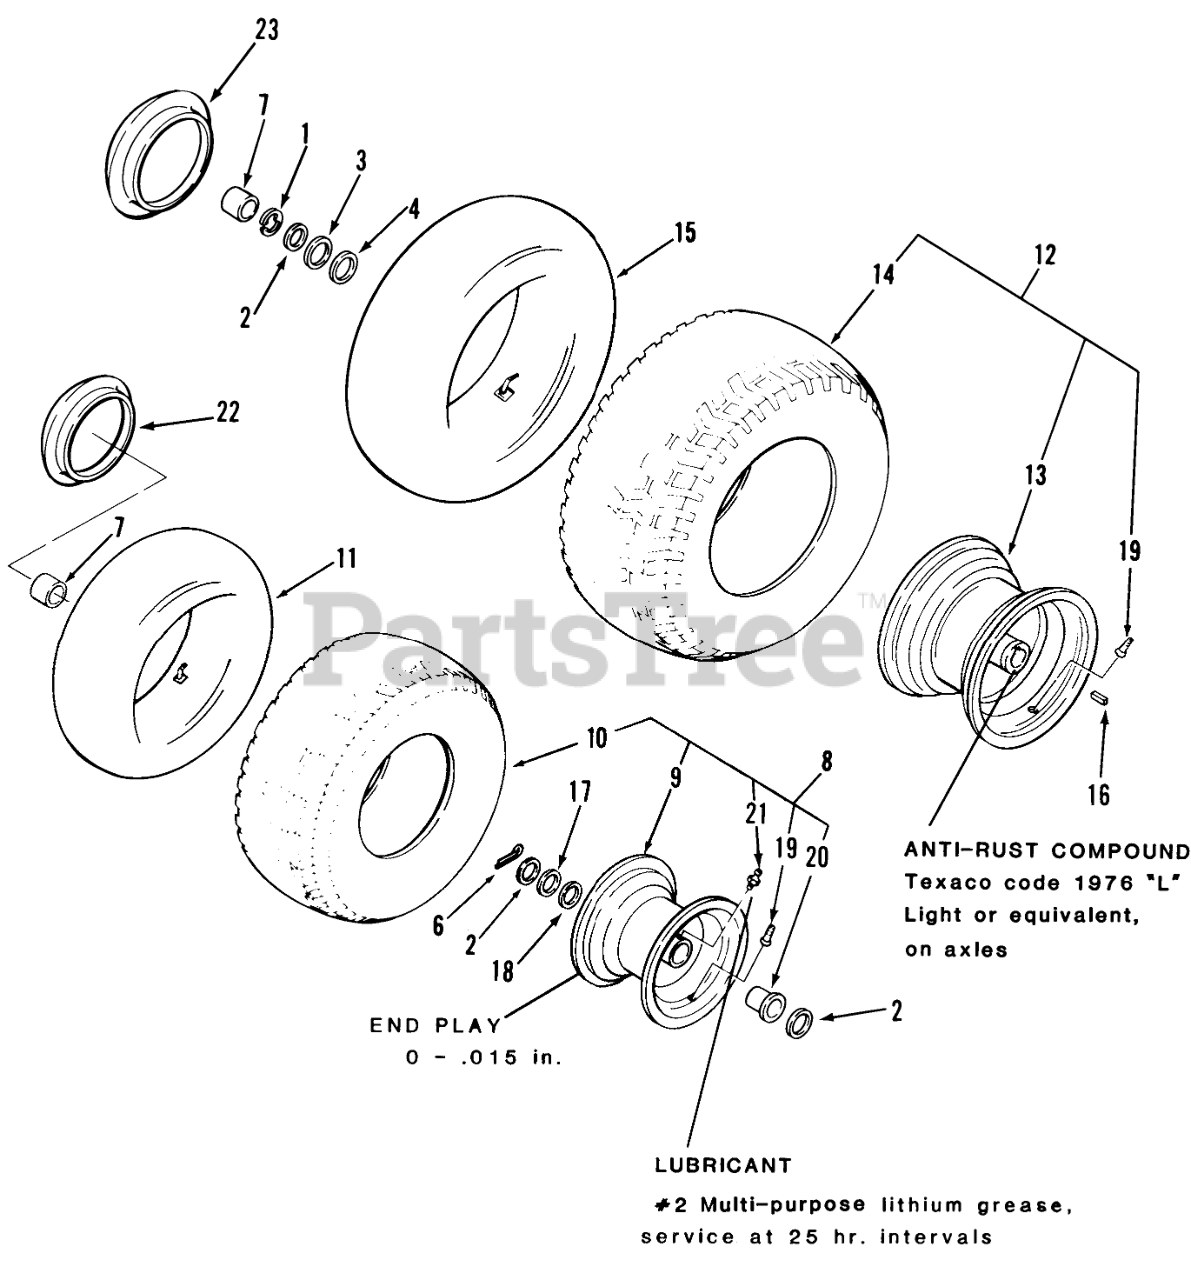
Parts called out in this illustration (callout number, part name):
1	E Ring
2	WASHER-FLAT
3	WASHER-SHIM
4	WASHER
6	COTTER PIN-4
7	HUB CAP
8	Assy-Wheel & Tire Front 208-3 Only
9	Front Wheel (includes Rim, items 19, 20 & 21) 203-3, 211-3 Only
10	Tire-Front 13 X 5.00-6
11	Front Tube-Service Only
12	Assy-Wheel & Tire-Rear 208-3 Only
13	ASSY WHEEL
14	TIRE
15	Rear Tube-Service Only
16	SQ KEY
17	WASHER
18	WASHER-SHIM
19	VALVE
20	FLANGE BEARING
21	ZERK-GREASE
22	HUB CAP 6 IN.
23	HUB CAP 10 IN.
